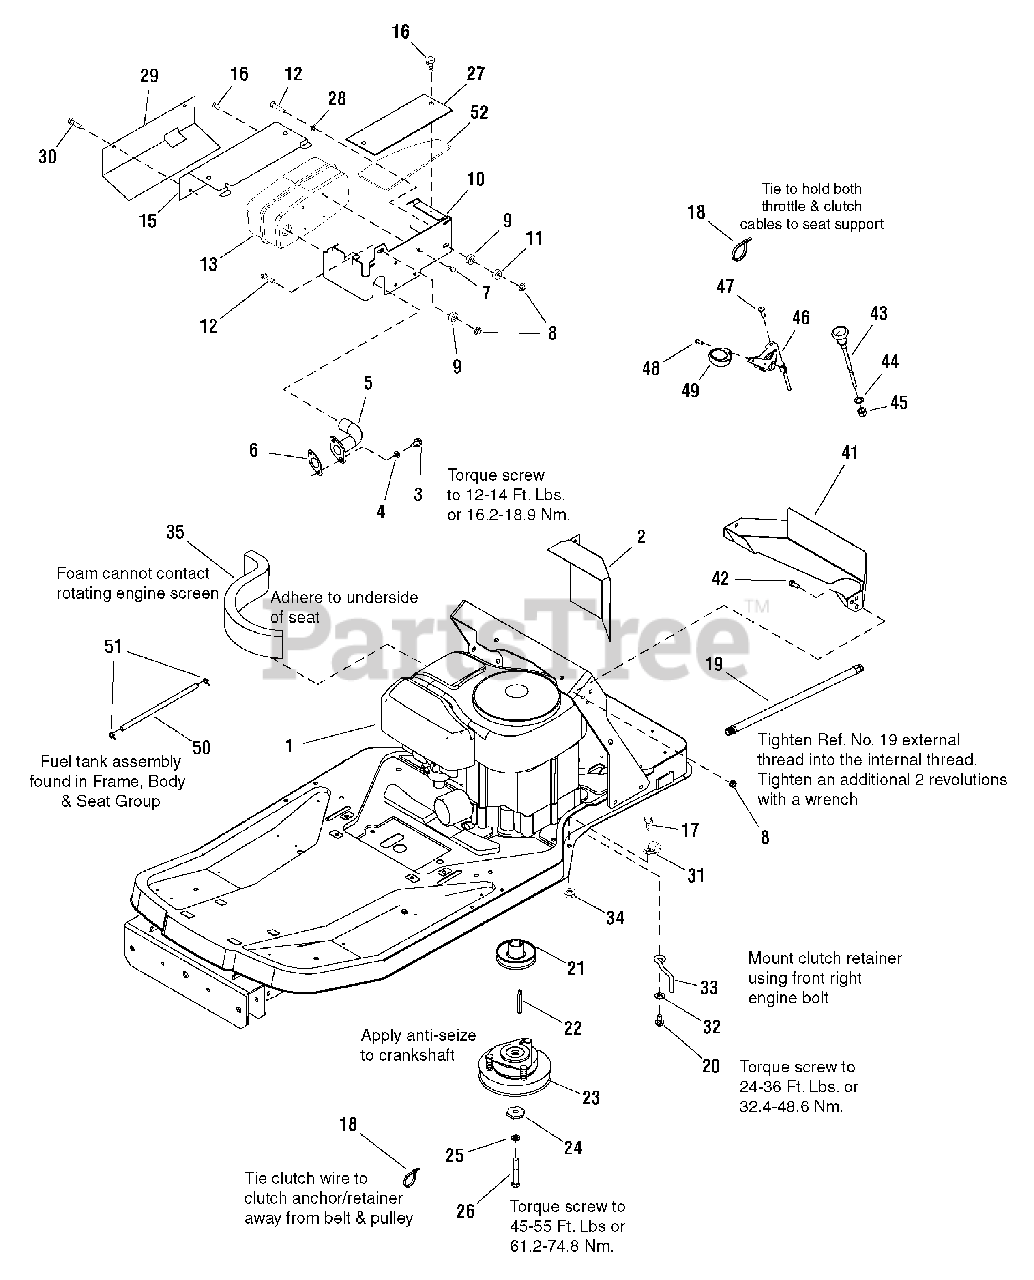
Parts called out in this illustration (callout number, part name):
1	* ENGINE, 21 HP, B&S, ELS
1	* ENGINE, 21 HP, B&S, ELS-California
1	* ENGINE, 21 HP, B&S, ELS (early models)
2	HEAT SHIELD, Inner
3	SCREW, 5/16-18 x 3/4" Hex Head Cap, GR8
4	LOCKWASHER, Spring 5/16", Black
5	WELDMENT, Exhaust Pipe
6	GASKET, Exhaust
7	SCREW, 1/4-20 x 5/8" Hex Whiz Lock Flange
8	NUT, 5/16-18 Hex Flange Lock Large Black
9	SPACER, .390 x .900 x .70, YZ
10	BRACKET, Muffler/Heat Shield
10	BRACKET, Muffler, Heat Resistant
11	SPACER, .390 I.D. x .90 O.D. x .34 Long, Powdered Metal
12	SCREW, 5/16-18 x 1-3/4" Hex Head Cap, GR5, YZ
13	MUFFLER ASSEMBLY, Single
15	HEAT SHIELD, Outer Single
16	SCREW, #10 x 1/2" Hex Washer Head Self-Tap
17	SCREW, 5/16-18 x 3/4" Hex Flange Lock
18	TIE, Self Locking 3-5/8" Long
19	HOSE, Oil Drain, 16-1/2" Long
20	SCREW, 3/8-16 x 1-1/4" Hex Washer Head Taptite
21	PULLEY, Engine- ZT
22	KEY, Square, 1/4 x 1/4 x 29/32 Hardened
23	CLUTCH, Ogura JD-11
24	WASHER, Hex, .453 I.D. x 1-1/2"
25	LOCKWASHER, Spring, .438
26	SCREW, 7/16-20 x 3" Hex Head Cap, GR5 (w/Nyloc Patch)
27	HEAT SHIELD
28	WASHER, 5/16" (.34 I.D. x 3/4" O.D.)
29	HEAT SHIELD
30	RIVET, Pop
31	CLIP, Harness, 5/8"
32	WASHER, 3/8", (.41 I.D. x .87 O.D. x .08 Thick)
33	RETAINER, Clutch
34	NUT, 5/16-18 Hex Whiz Lock Flange
35	SEAL, Foam 1.0 x 3.50 x 12" Long
41	AIR DUCT, Inlet
42	SCREW, 5/16-18 x 3/4" Hex Head Cap, Black
43	CABLE, Choke, 54"
43	ASSY, Choke-a-Matic Control
44	WASHER, 3/8" Internal Tooth Lock
45	NUT, 3/8-24 Hex
46	CONTROL, Throttle B&S Intek
47	SCREW, 1/4-20 x 5/8" Pan Head Taptite Torx
48	SCREW, #10-16 x 3/4" Pan Head Taptite Combo
49	KNOB, Throttle, Red
50	** HOSE, Fuel, Low Perm, 1/4" I.D. x 19-1/2" Long
51	CLAMP, Fuel Hose
52	INSULATION, Muffler Shield
